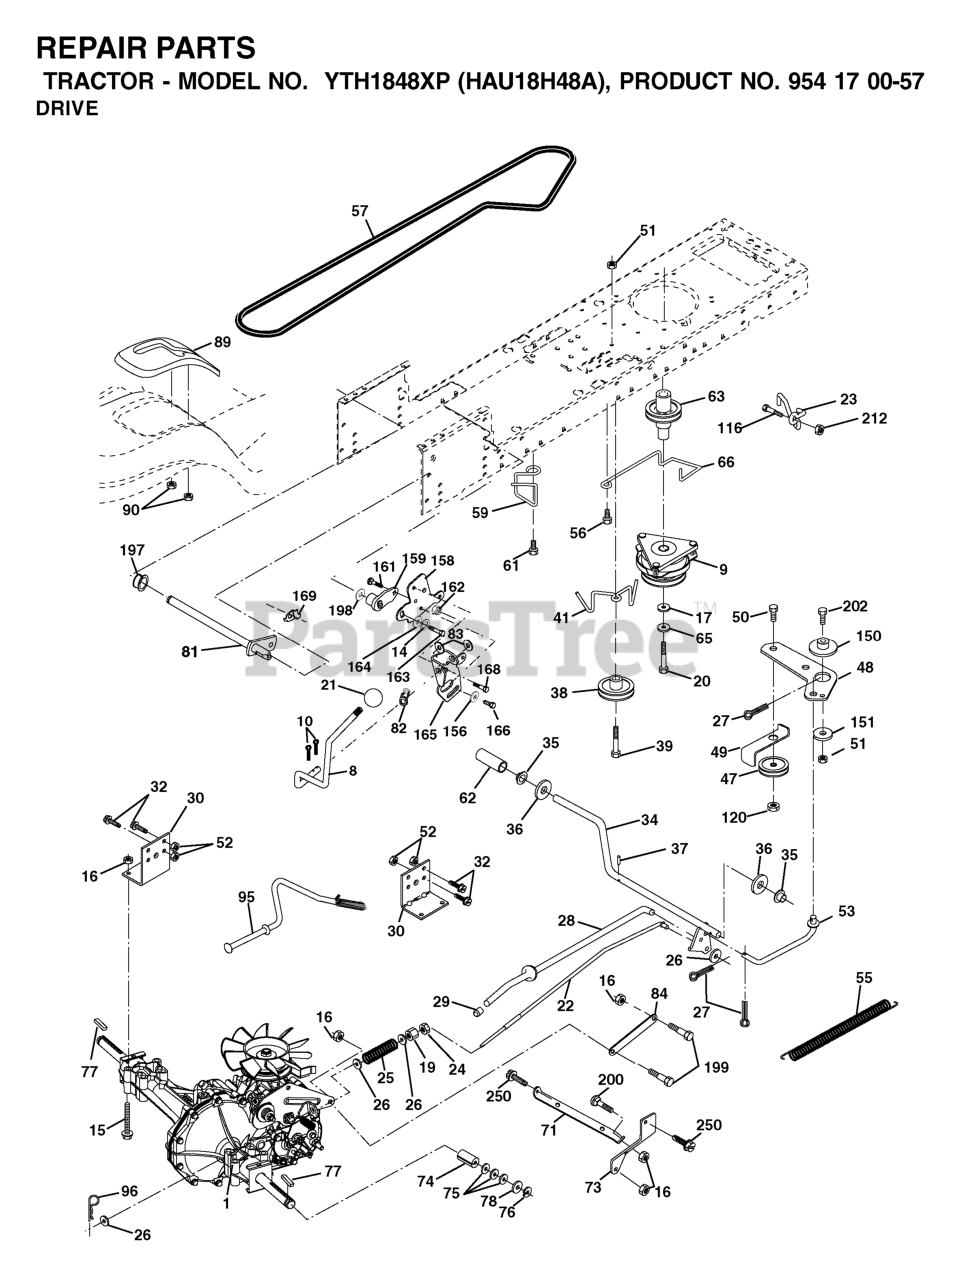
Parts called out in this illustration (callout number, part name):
8	ROD SHIFT FENDER ADJUST STLT
9	CLUTCH, ELECTRIC
10	PIN COTTER
14	LOCKWASHER
15	BOLT HEX 5/16-18 GR 5
16	NUT.71038.31-18.HEX.NYLOCK
19	NUT
20	BOLT HEX 7/16-20X4-1/4"
21	KNOB.DELUXE.(PISTOL.GRIP).BLAC
22	ROD BRAKE HYDRO
23	BRKT ASM MTNG
24	NUT
25	SPRING ROD LT
26	WASHER
27	COTTER PIN
28	ROD, PARKING BRAKE
29	PLUNGER CAP
30	BRKT, TRNSXLE MNT 20"
32	BOLT
34	SHAFT, FOOT PEDAL
35	BEARING.NYLON
36	WASHER LT
37	DRIVE PIN
38	PULLEY IDLER COMPOSITE
39	BOLT
40	SPACER, SPLIT
41	KEEPER, BELT IDLER
42	WASHER
47	IDLER PULLEY
48	BELLCRANK, CLUTCH
49	RETAIN BELT
50	BOLT
52	LOCKNUT
53	LINK, CLUTCH LT
55	SPRING, RETURN LT
56	SCREW.3/8-16
57	DRIVE BELT, LTH & YTH TRACTORS
59	KEEPER, BELT CENTER
61	SCREW 3/8-16X.875
62	PEDAL COVER T
63	PULLEY, ELEC CLUTCH
65	LOCKWASHER
66	KEEPER BELT ENGINE
71	STRAP TORQUE LH HYDRO
73	STRAP TORQUE RH HYDRO
74	SPACER AXLE
77	SQUARE KEY
81	SHAFT ASM CROSS TAPERED
82	SHIFT SPRING
83	WASHER
84	LINK TRANSAXLE
89	SHIFT CONSOLE
90	NUT.PUSH.3/16
95	CONTROL ASM. BYPASS HYDRO
96	RETAINER M
116	BOLT D
120	NUT LOCK FLG 3/8-16 UNC
150	SPACER, RETAINER
151	WASHER 12/32X2X10GA
156	WASHER.SRRTD.5/16
158	BRACKET
159	HUB
161	BOLT
162	NUT.CROWNLOCK.1/4
163	BOLT
164	Washer 5/8 x .281 x 10 Ga.
165	RP BRACKET
168	BOLT.SHOULDER.5/16-18X
169	PLATE.FASTENING.CROSS.SHAFT
197	NYLINER SNAP 5/8" ID
198	WASHER.NYL.7/8IDX.105"HYD CR
199	BOLT SHOULDER 5/16-18 UNC
200	BOLT
202	BOLT.3/8-16X1.50
212	NUT
250	SCREW 3/8-16X3/4
